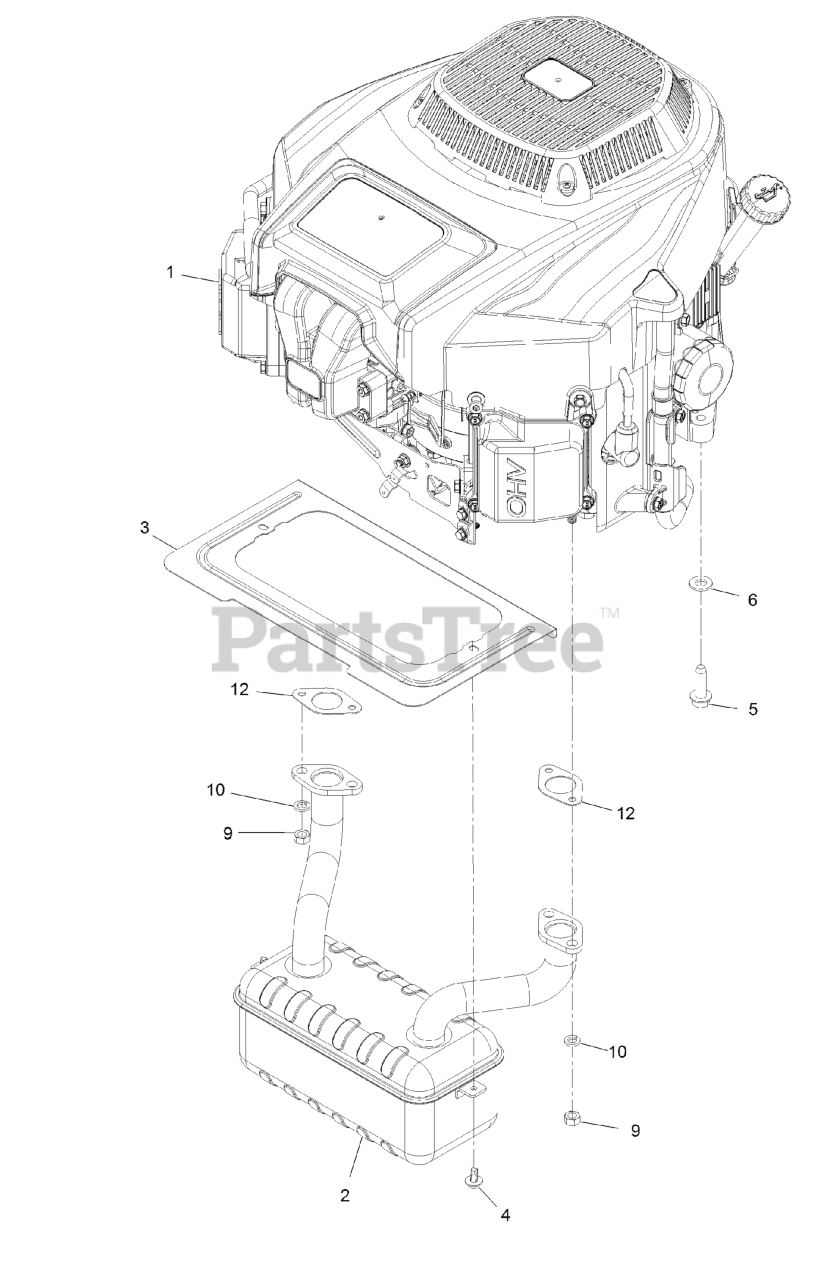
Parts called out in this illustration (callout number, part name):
1	ENGINE-2P77F
2	MUFFLER
3	SHIELD-HEAT
4	SCREW-HHFTF
5	SCREW-THD
6	WASHER-FLAT
10	WASHER-LOCK, SPLIT
12	GASKET-EXHAUST
